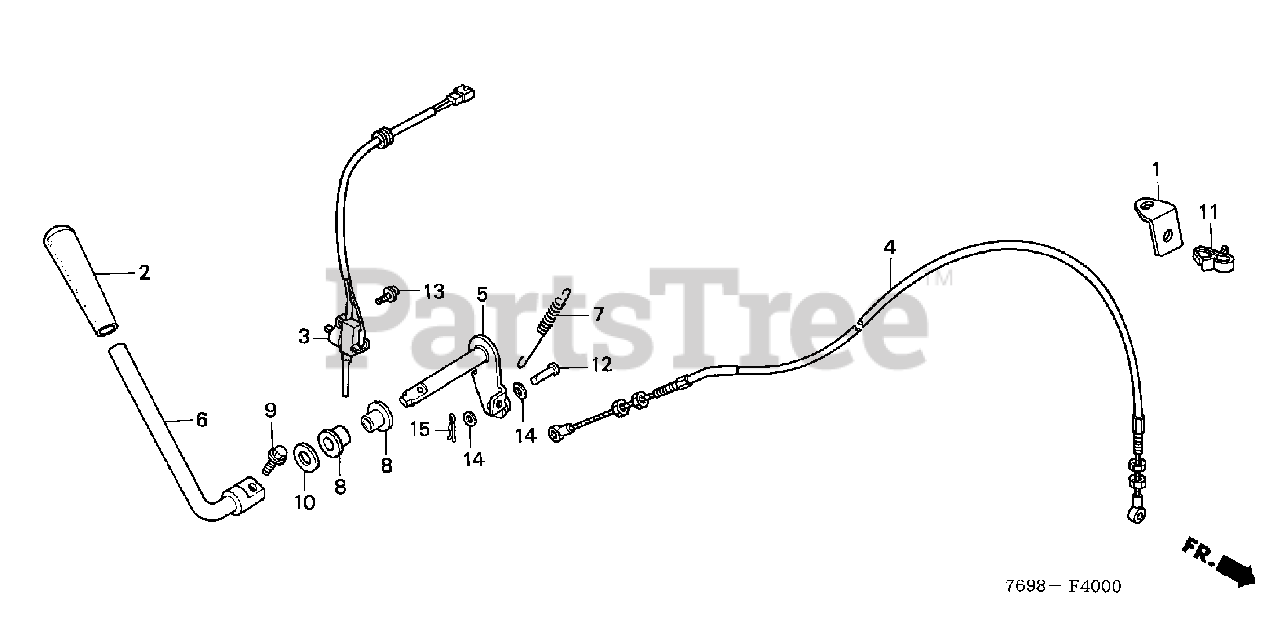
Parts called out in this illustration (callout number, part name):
1	BRACKET, P.T.O. CABLE CLAMP
2	GRIP, P.T.O. CLUTCH LEVER *Y121* (YELLOW)
3	SWITCH ASSY., P.T.O. CLUTCH
4	CABLE, P.T.O. CLUTCH
5	ARM, P.T.O. CLUTCH LEVER
6	LEVER, P.T.O. CLUTCH
7	SPRING, P.T.O. CLUTCH
8	BUSH, P.T.O. CLUTCH ARM
9	BOLT, FLANGE (6X12)
10	WASHER (14MM)
11	CLIP, WIRE HARNESS
12	PIN, AUXILIARY CHANGE LEVER JOINT
13	SCREW-WASHER (4X12)
14	WASHER, PLAIN (6MM)
15	PIN, LOCK (6MM)
